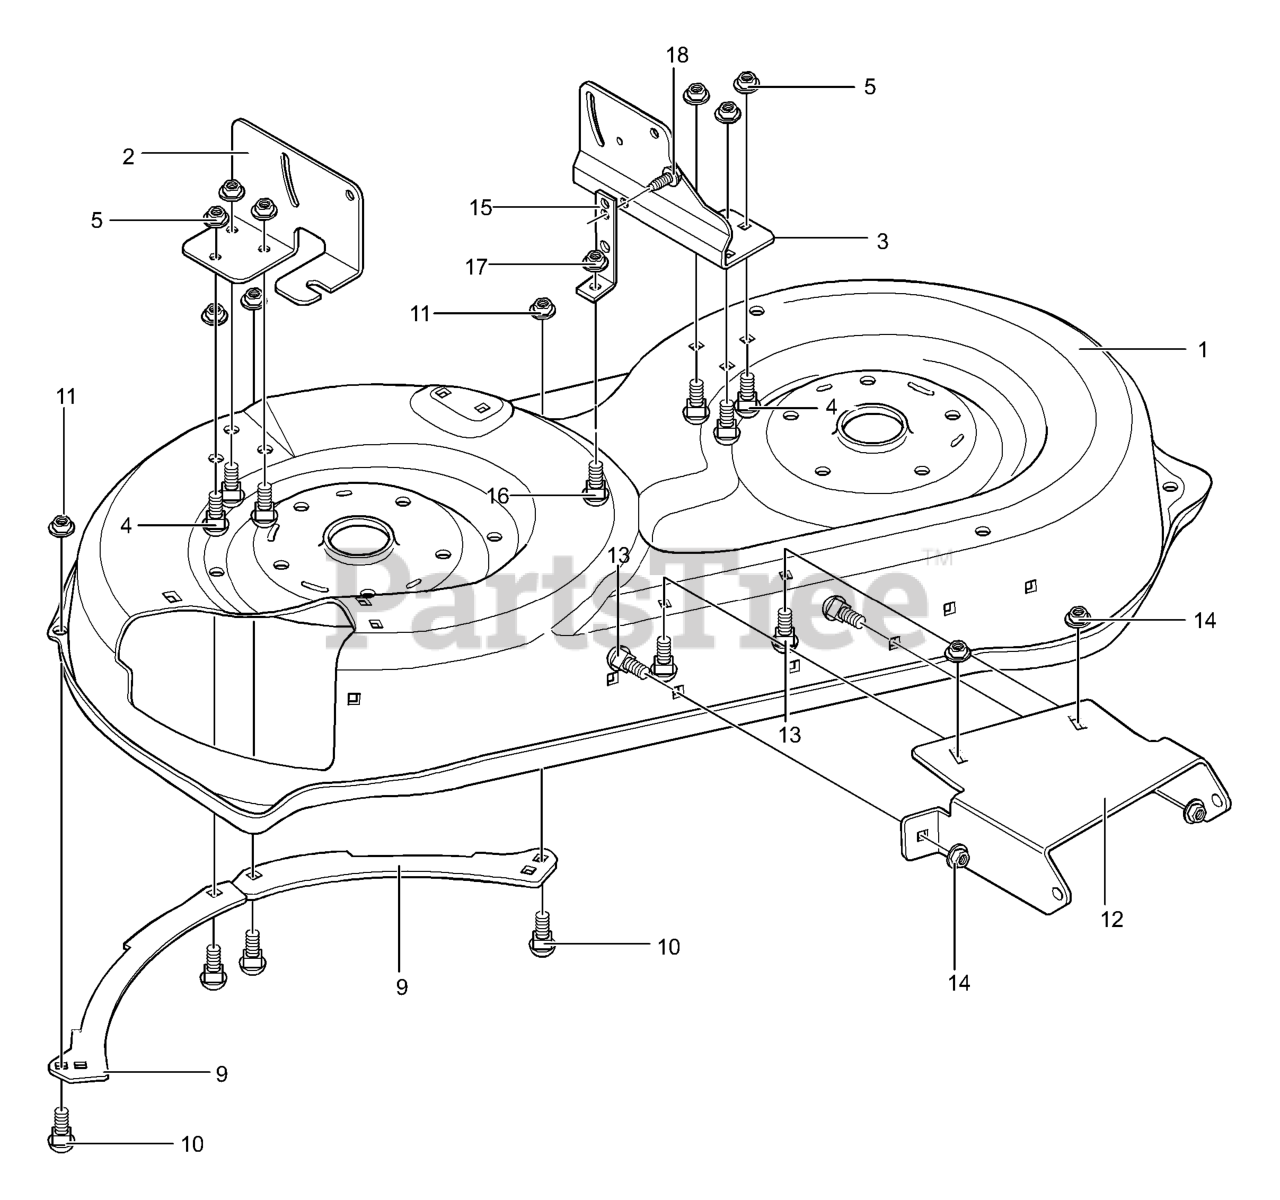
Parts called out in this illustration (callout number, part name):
1	MOWER DECK, 38"
2	Bracket, Deck Lift RH
3	Bracket, Deck Lift LH
4	Bolt, .31-18x.62
5	Nut, .32-18 Flangelock
9	Toeguard, Flange
10	Bolt, .31-18x.62
11	Nut, .32-18 Flange Centerlock
12	Bracket, Front Deck
13	Bolt, .31-18x.062
14	Nut, .32-18 Flangelock
15	Bracket, Support
16	Bolt, .31-18x.62
17	Nut, .32-18 Flangelock
18	Screw, .312-18x.75
